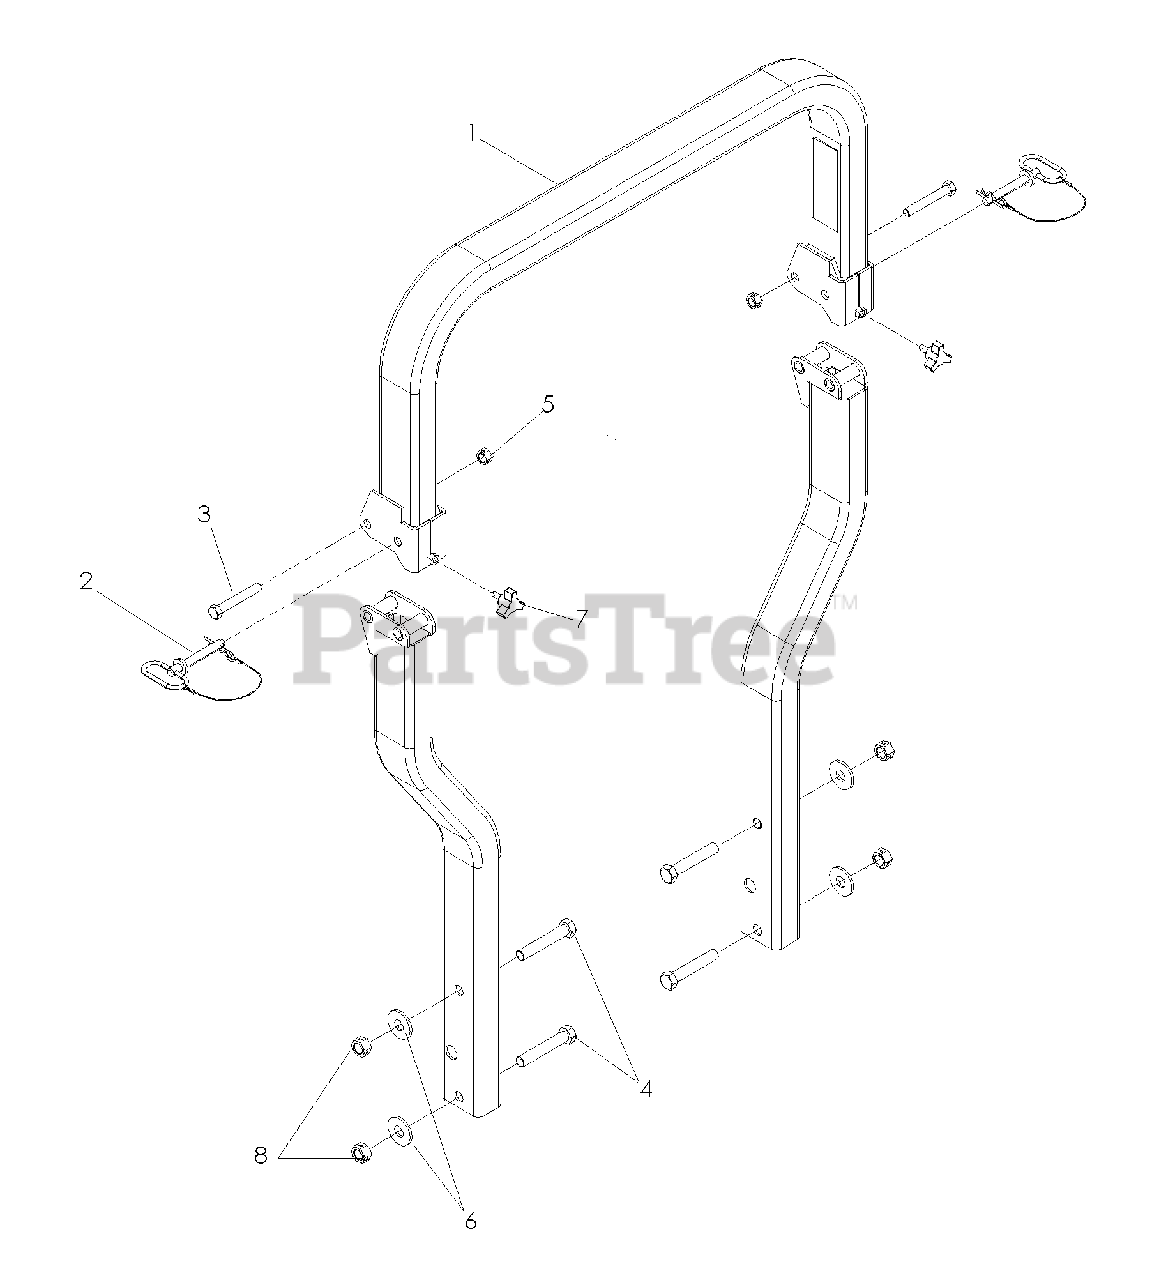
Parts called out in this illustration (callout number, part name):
1	ROPS, COMPLETE, W/SEAT BELT
2	PIN 1/2 W/LANYARD
3	HCS 1/2-13 x3 1/4
4	HCS 5/8-13 x3
5	NUT 1/2-13 HEX CNTRLK
6	WASHER 5/8 STD
7	KNOB w/STUD
8	NUT 5/8-11 HEX CNTRLK
